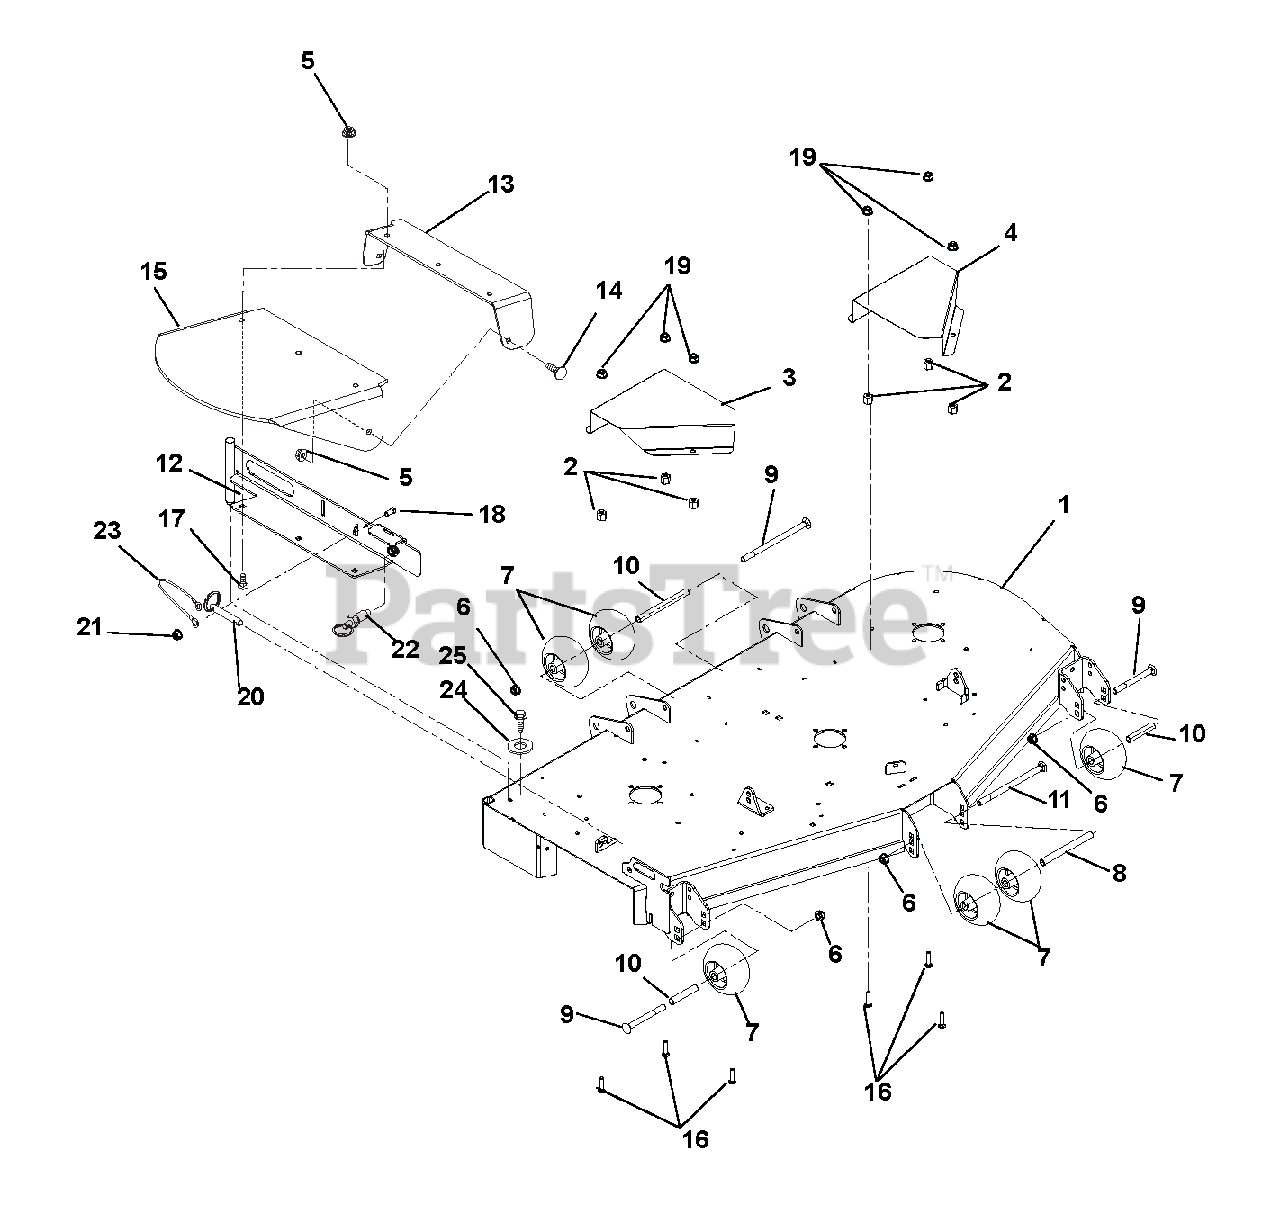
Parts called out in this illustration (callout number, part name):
1	KIT,DECK - 60" W/SAFETY DECALS
1	KIT,DECK - 52" W/SAFETY DECALS
1	KIT,DECK - 48" W/SAFETY DECALS
2	NUT-HEAVY HEX .38-16 YWZC
3	60" RH BELT GUARD
3	GUARD-44-52 RH SPINDLE SHEAVE
4	60" LH BELT GUARD
4	44-52" LH DECK BELT GUARD
5	@NUT-LK-NYL-FLG .38-16 YWZC
6	@NUT-LK-NYL-FLG .50-13 YWZC
7	ANTI-SCALP WHEEL - 5X3 CTR
8	SPACER, .510X.625X6.50
9	BLT-RDHDSQNK .50-13X5.00 GR5YZ
10	SPACER, .510X.625X3.35
11	@BLT-RDHDSQNK .50-13X8.50 G5YZ
12	WMT, 44"-48" DISCH CHUTE MTG
12	WMT, 52"-60" DISCH CHUTE MTG
13	SUPPORT, RUBBER DISCH CHUTE
14	@BLT-RDHDSQNK .38-16X1.00 G5YZ
15	CHUTE, RUBBER DISCHARGE
16	@BLT-HEX .38-16X1.25 GR5 YWZC
17	@BLT-RDHDSQNK .38-16X1.25 G5YZ
18	@BLT-HEX .25-20X.75 GR5 YWZC
19	@NUT-SPNLK-FLG .375-16 YWZC
20	PIN, SPRING BALL .375OD X 1.50
21	@NUT-LK-TOP-FLG .25-20 YWZC
22	PULL PIN,.50-13THDX.310 PLNGR
23	CABLE, 6.0 LANYARD, NYLON
24	BUMPER,RECESSED1.50X.63 W/.31
25	@SCR-TAP .31-18X.75 HWH TR YWZ
